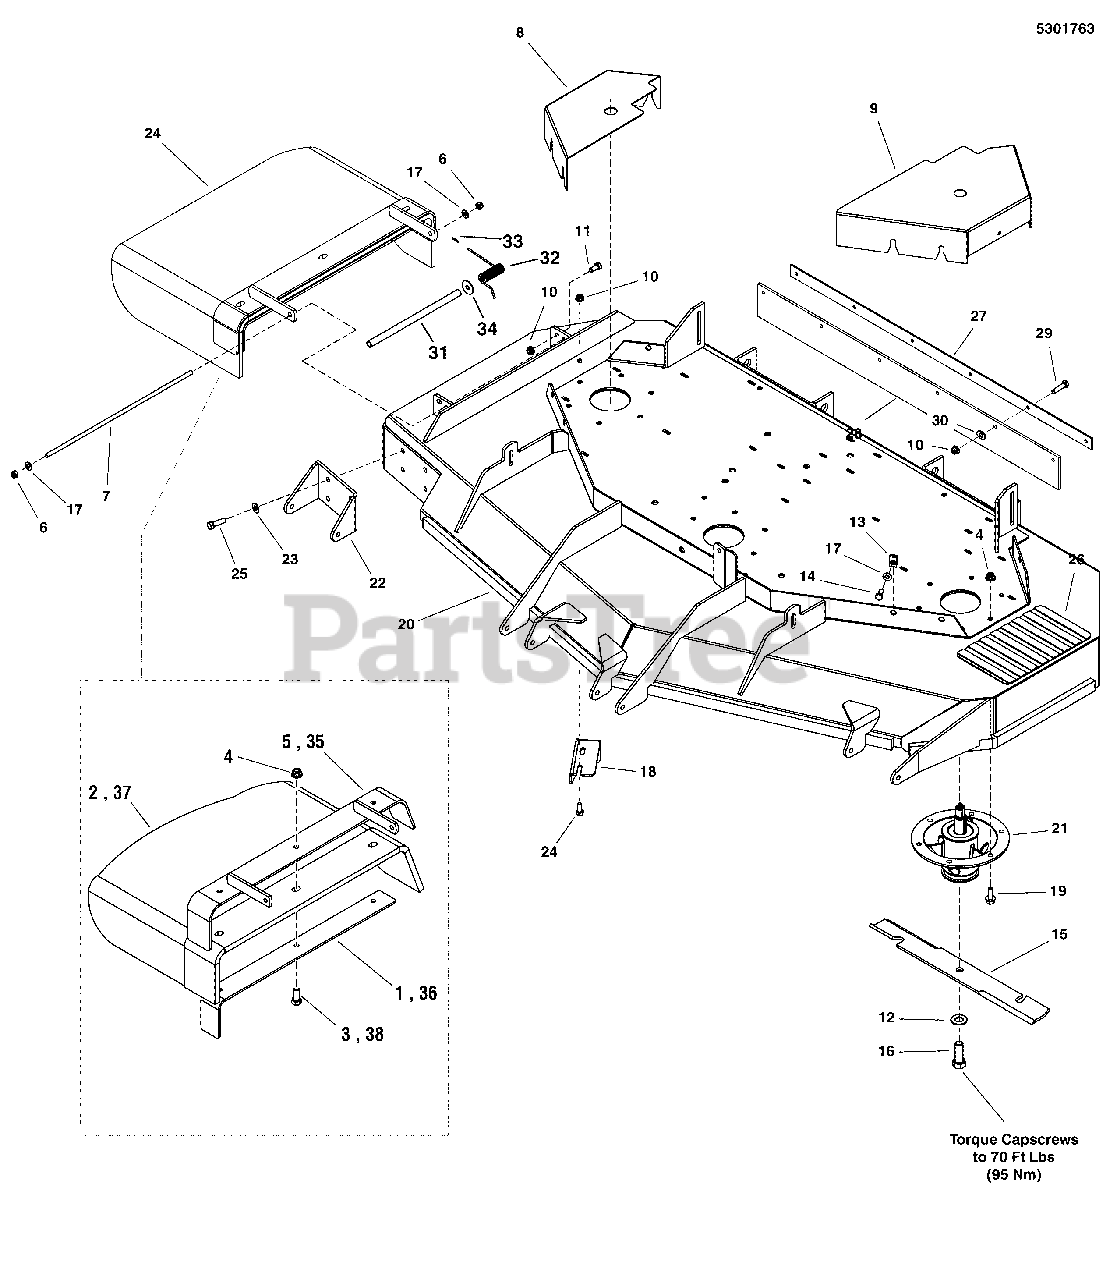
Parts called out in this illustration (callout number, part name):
1	SUPPORT, DISCHARGE CHUTE, 61/72 - BLK
2	CHUTE, DISCHARGE, BEND RUBBER (SV)
3	BOLT, 3/8-16 X 1-1/2 GD5 YZ
4	NUT, 3/8-16 HEX NYLOCK FLANGE
5	WELD, FRAME CHUTE, 61 - BLK
6	NUT, 5/16-24 HEX NYLON LOCK
7	ROD MOUNT, CHUTE 61"
8	GUARD, RH - 61 - S200XI - RED
9	GUARD, 61 - LH - RED
10	NUT, 5/16-18 HEX NYLOCK FLANGE
11	SCREW, 5/16-18
12	WASHER, 5/8 GRADE 8, YZ
13	BODY CLIP, 5/16-18-7GA MATERIAL
14	BOLT, 5/16-18 X 3/4 GD5
15	BLADE, 21 X .25 X 2.5, 1 X 3.5 (SET OF 3)
16	BOLT, 5/8-11 X 1-3/4 GD8
17	WASHER, 5/16" SAE
18	PLATE, DEFLECTOR - BLK
19	BOLT, 3/8-16 X 1, FLANGE
20	DECK SHELL W/ DECALS, 61"
20	DECK SHELL W/ DECALS, 200XT 61 - SPR RED
20	DECK SHELL W/DECALS,61,200XT-SPR/MASS
21	SPINDLE ASSM, CAST IRON 8.0-6 BOLT
22	PLATE, BRACKET, ANTI SCALP - RED
23	WASHER, 3/8 SAE
24	BOLT, 5/16-18 X 3/4, CARRIAGE
25	BOLT, 3/8-16 X 1-1/4 GD5
26	SAFETY WALK, 9.75 X 6.00
27	PLATE, SUPPORT - BLK
28	FLAP, STRIPER, 61 DECK
29	BOLT, 5/16-18 X 1 GD5 YZ
30	5/16 PUSH-ON NUT RETAINER, STL, CZ
31	TUBE, 1/2 X 3/8 X 10.75 BLACK POLY
32	SPRING, TORSION
33	CAP, PROTECTOR, .120 ID
34	WASHER, 5/16 FENDER
35	WELD, MOUNT, DISCHARGE CHUTE - BLK
36	SUPPORT, DISCHARGE CHUTE - BLK
37	CHUTE, RUBBER DISCHARGE (5104442)
38	BOLT, 3/8-16 X 1-1/2, CARRIAGE, GD5, CZ
